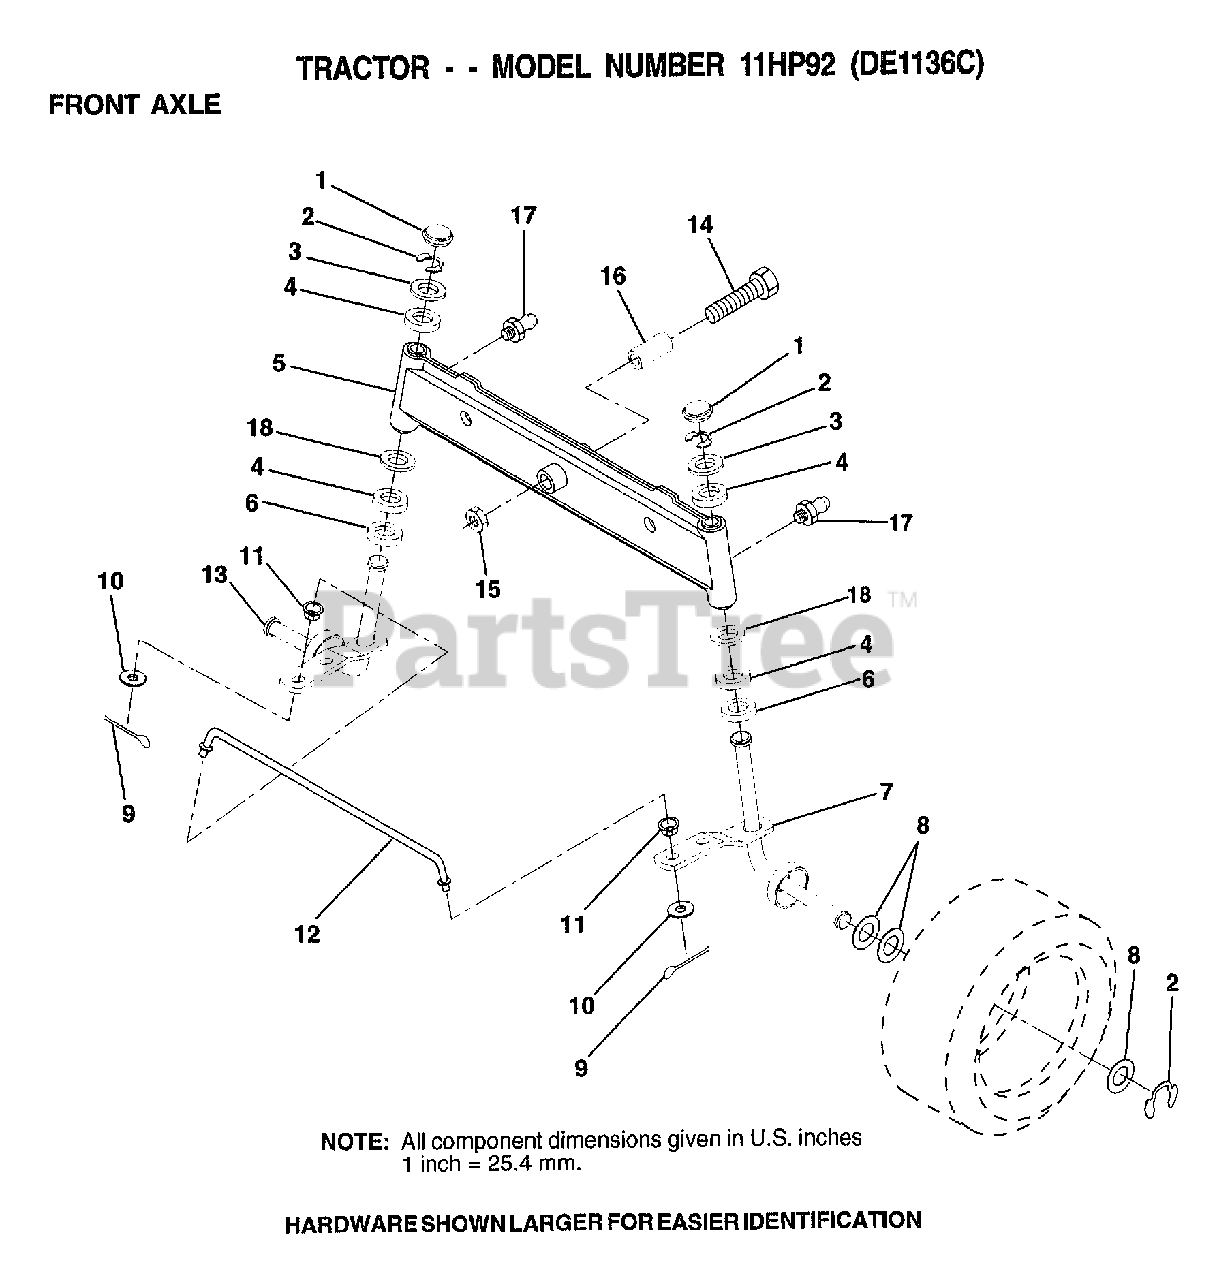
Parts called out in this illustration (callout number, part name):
1	CAP
2	RING
3	WASHER
4	COL. SRTG. BEAR.
5	AXLE ASM FRONT
6	WASHER .T
7	SPINDLE.ASSY.RH
8	WASHER
9	COTTER PIN
10	WASHER
11	BUSHING.DRAGLINK
12	TIE ROD
13	SPINDLE.ASSY.LH
14	BOLT HEX 5/8-11
15	"NUT-LOC,FLANGE LT"
16	BEARING
17	ZERK M
18	WASHER
